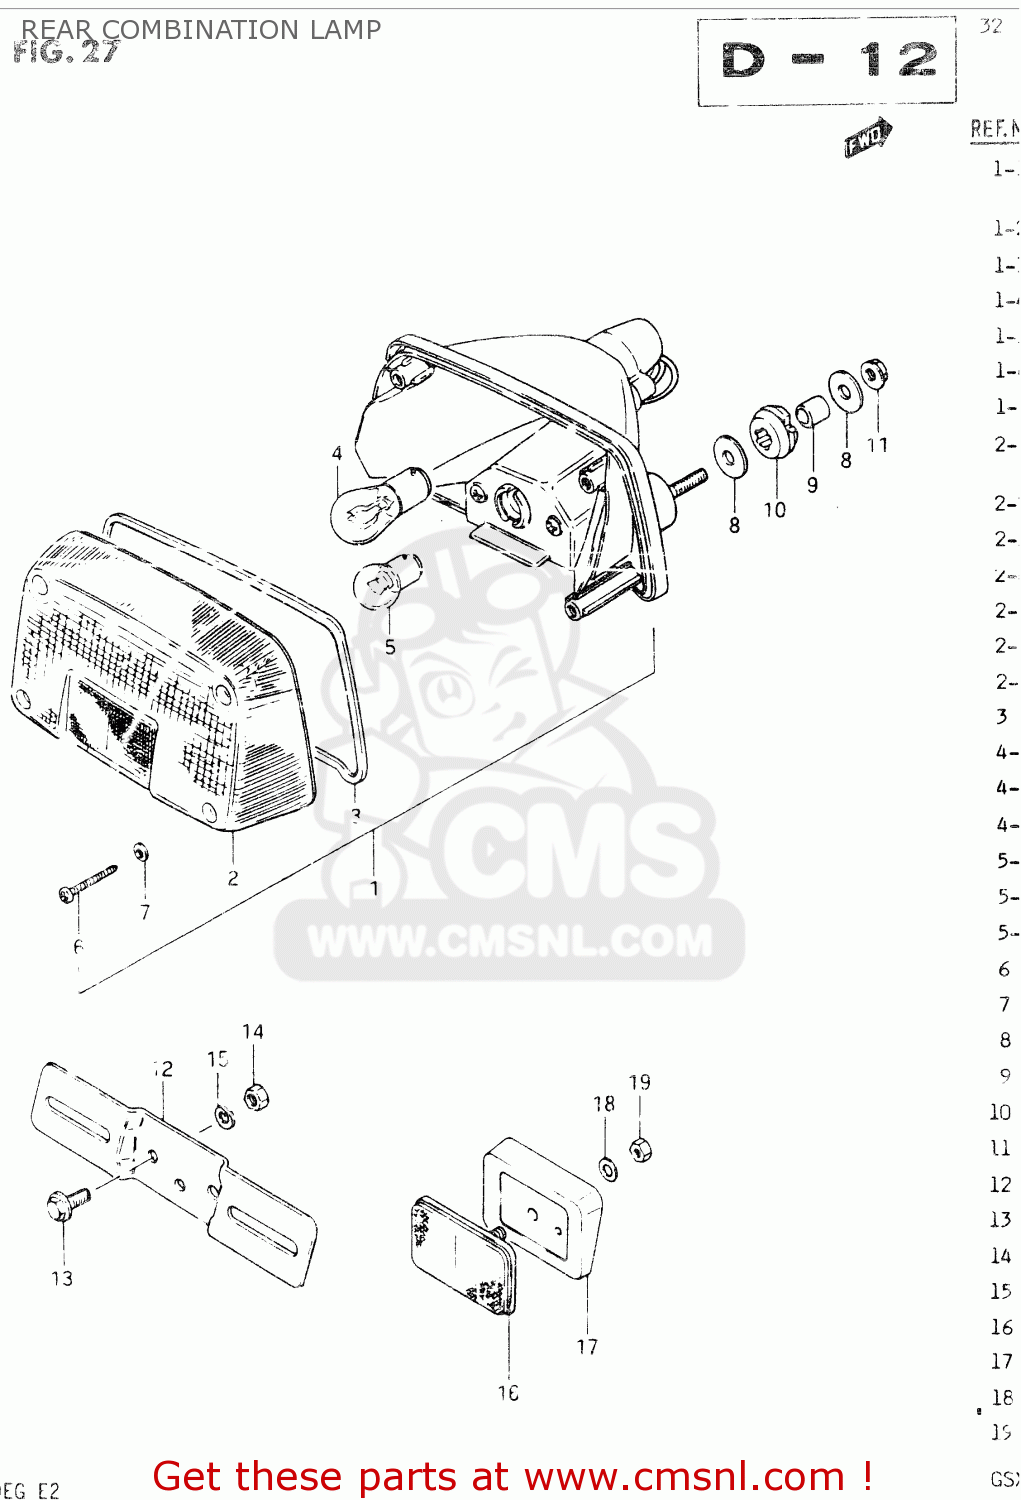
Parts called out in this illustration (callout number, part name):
1	LAMP ASSY, REAR COMBINATION
2	LENS
3	GASKET
4	BULB(12V23W)
5	BULB
6	SCREW
7	GASKET (NAS)
8	WASHER
9	SPACER (6.8X10X11.5)
10	CUSHION
11	NUT
12	BRACKET, LICENSE PLATE
13	BOLT
14	NUT
15	WASHER,LOCK
16	REFLECTOR,REFLEX
17	SPACER
18	WASHER(5.2X16X1)
19	NUT
